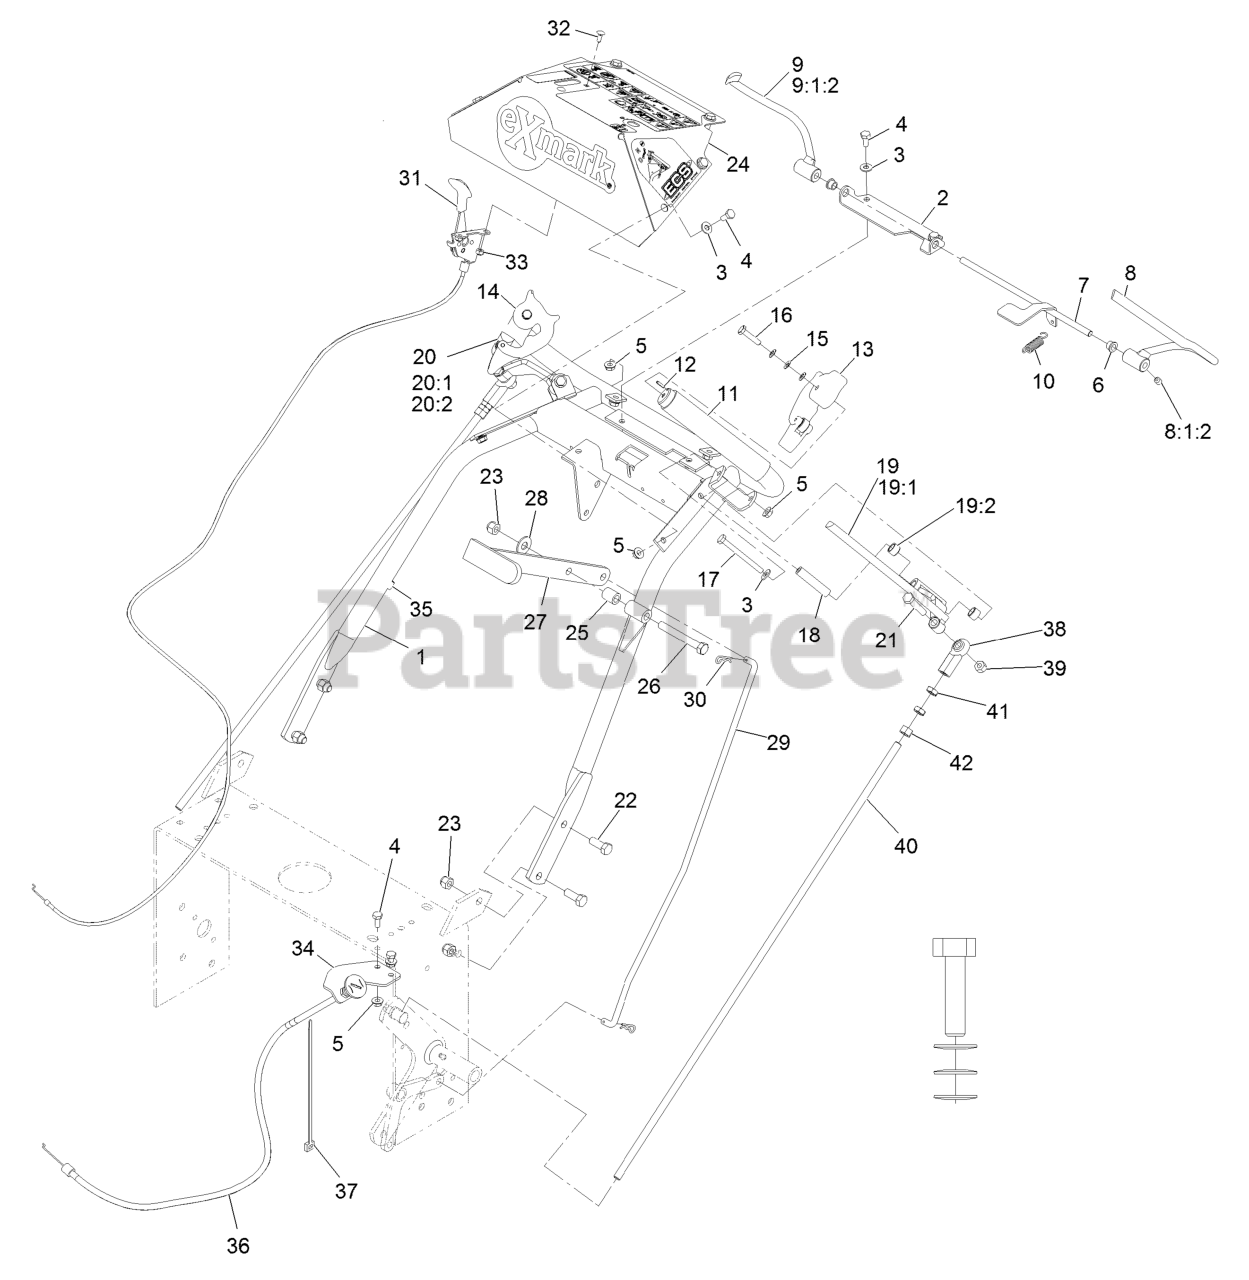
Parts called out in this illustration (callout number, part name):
1	WLD,UPPER ECS HANDLE
2	BRACKET,OPC AXLE
3	WASHER-FLAT
4	SCREW-HH
6	BUSHING-NYLON
7	WLD,OPC LEVER AXLE
8	WLD,LH OPC LEVER
8:1:2	SCREW-SET
9	WLD,RH OPC LEVER
9:1:2	SCREW-SET
10	SPRING-EXTENSION
11	GRIP-BAR, HANDLE
12	PIN-SPRING
13	ASM,LH THUMB LATCH
14	ASM,RH THUMB LATCH
15	WASHER-SPRING
16	SCREW-HH
17	SCREW-HH
18	BUSHING-LEVER, DRIVE
19	DRIVE LEVER-ASM, LH
19:1	WLD,LH DRIVE LEVER
19:2	BUSHING-SLEEVE
20	DRIVE LEVER-ASM, RH
20:1	WLD,RH DRIVE LEVER
20:2	BUSHING-SLEEVE
21	SCREW-HH
22	SCREW-HH
23	NUT-LOCK, NI
24	ASM, CONSOLE W/DECALS
25	BUSHING-LEVER, LIFT
26	SCREW-CARR
27	CLUTCH LEVER-W/GRIP
28	WASHER-FLAT
29	LINKAGE,UPPER BLADE (PLT)
30	PIN-COTTER
31	CONTROL, THROTTLE
31	Control, Throttle
32	BOLT-CARR
33	NUT-LOCK, NI
34	BRACKET-CABLE, CHOKE
35	CLIP-CABLE
36	CABLE-CHOKE
36	Cable-Choke
37	TIE-PLASTIC
38	JOINT-BALL, END
39	NUT-LOCK, NI
40	LINKAGE,DRIVE (PLT)
41	NUT-HJ
42	NUT-HEX
